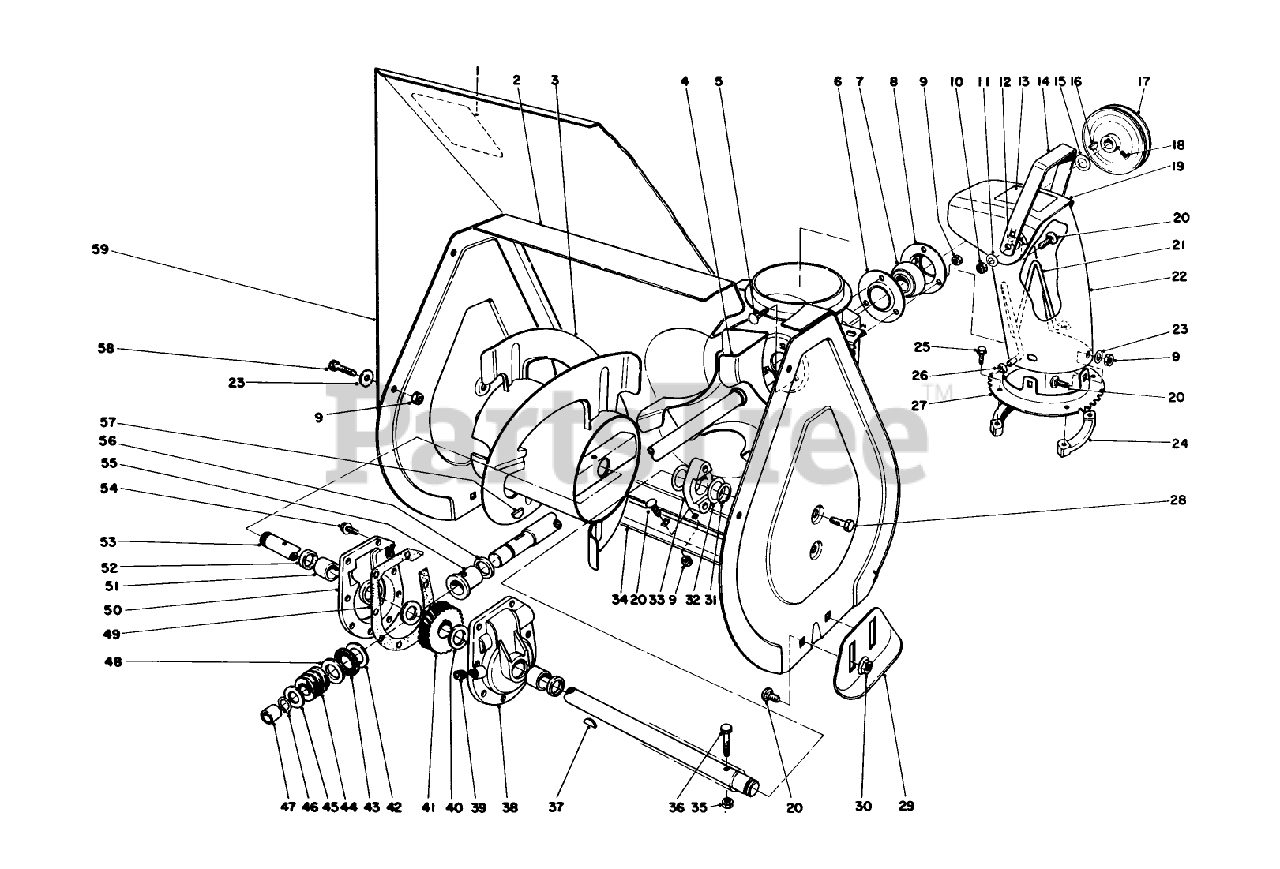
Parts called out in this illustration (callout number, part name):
1	DECAL-WARNING, AUGER
2	Housing-Auger (Incl. Ref. #1)
3	Auger R.H.
4	Shaft & Impeiler
5	BOLT-CARR
6	FLANGE-CUP, BEARING
7	Ball Bearing
8	FLANGE-CUP, BEARING
9	NUT-LOCK, NI
10	NUT-LOCK, CONE
11	WASHER-BELLEVILLE
12	WASHER-RUBBER
13	Decal-Danger
14	Handle Deflector
15	WASHER
16	KEY-WOODRUFF
17	PULLEY
18	SCREW-SET, SQH
19	Deflector (Incl. Ref. #13)
20	BOLT-CARR
21	CHUTE WIRE
22	DISCHARGE CHUTE
23	WASHER-PLAIN
24	RING-CHUTE, RETAINER
25	SCREW-SPECIAL
26	NUT-PUSH
27	Chute Ring
28	SCREW-HWHTF
29	Skid
30	NUT-HF
31	RING-RETAINING
32	WASHER
33	BEARING-AUGER
34	Blade-Scraper
35	NUT-LOCK, CONE
36	SCREW-HH
37	KEY-WOODRUFF
38	Gear Case L.H. (Incl. Ref. #51 & 52)
39	PLUG-PIPE, SQH
40	WASHER-THRUST
41	Gear
42	WASHER-THRUST
43	BEARING-THRUST
45	WASHER-THRUST
46	Ring-Snap
47	BUSHING
48	WASHER-THRUST
49	GASKET-CASE, GEAR
50	Gear Case R.H. (Incl. Ref. #51 & 52)
51	BUSHING
52	SEAL-OIL
53	AUGER SHAFT
54	SCREW-TAPTITE
55	BUSHING-INPUT
56	RING-QUAD
57	KEY-WOODRUFF
58	SCREW-HH
59	AUGER EXT 21 SCAND
